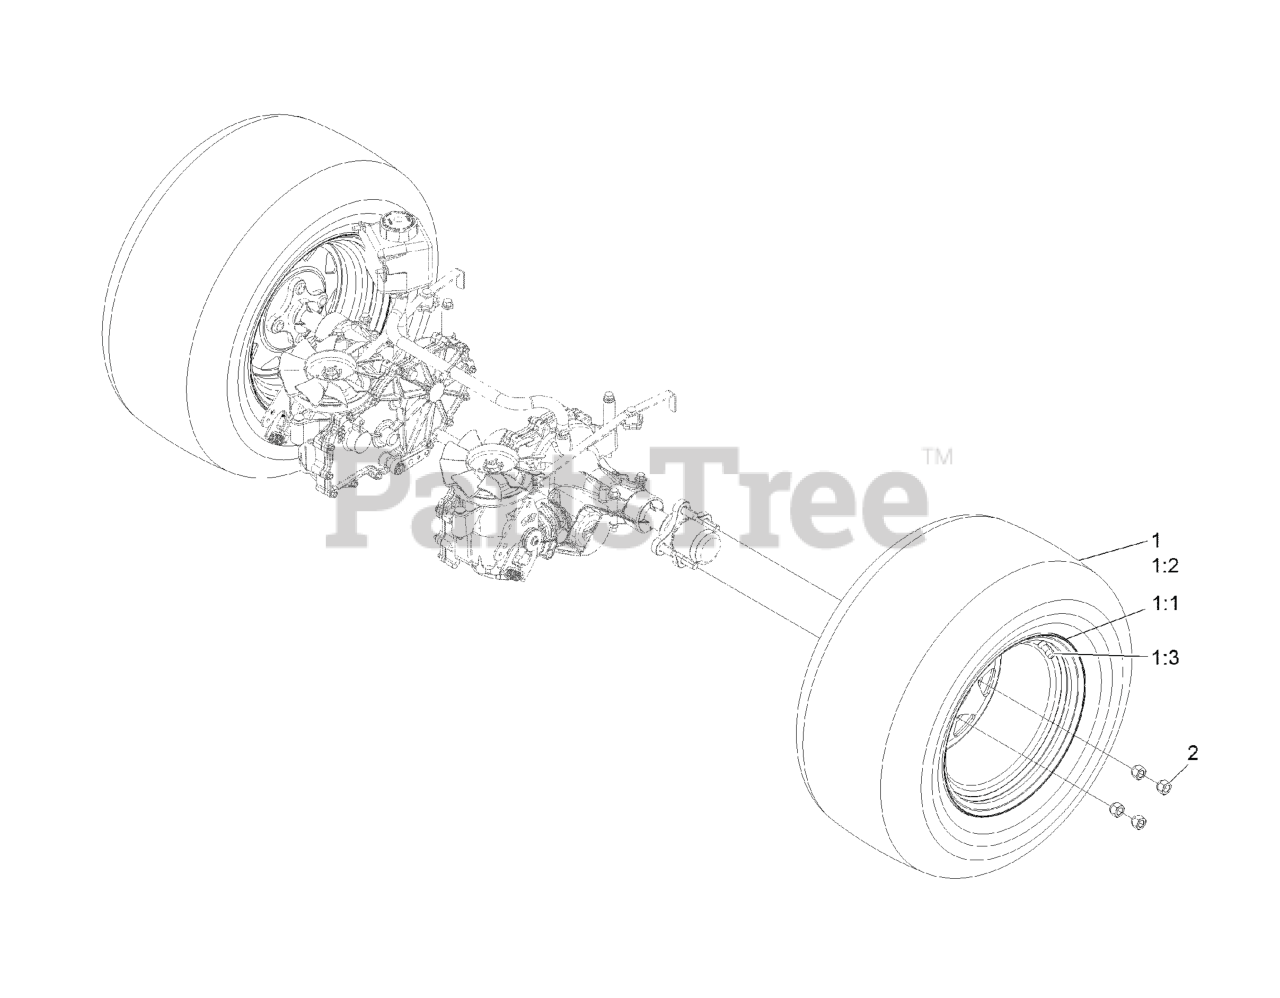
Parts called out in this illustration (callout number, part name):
1	WHEEL AND TIRE ASM
1:1	WHEEL RIM 12X8.5
1:2	TIRE
1:3	Stem-Valve
2	NUT-LUG
